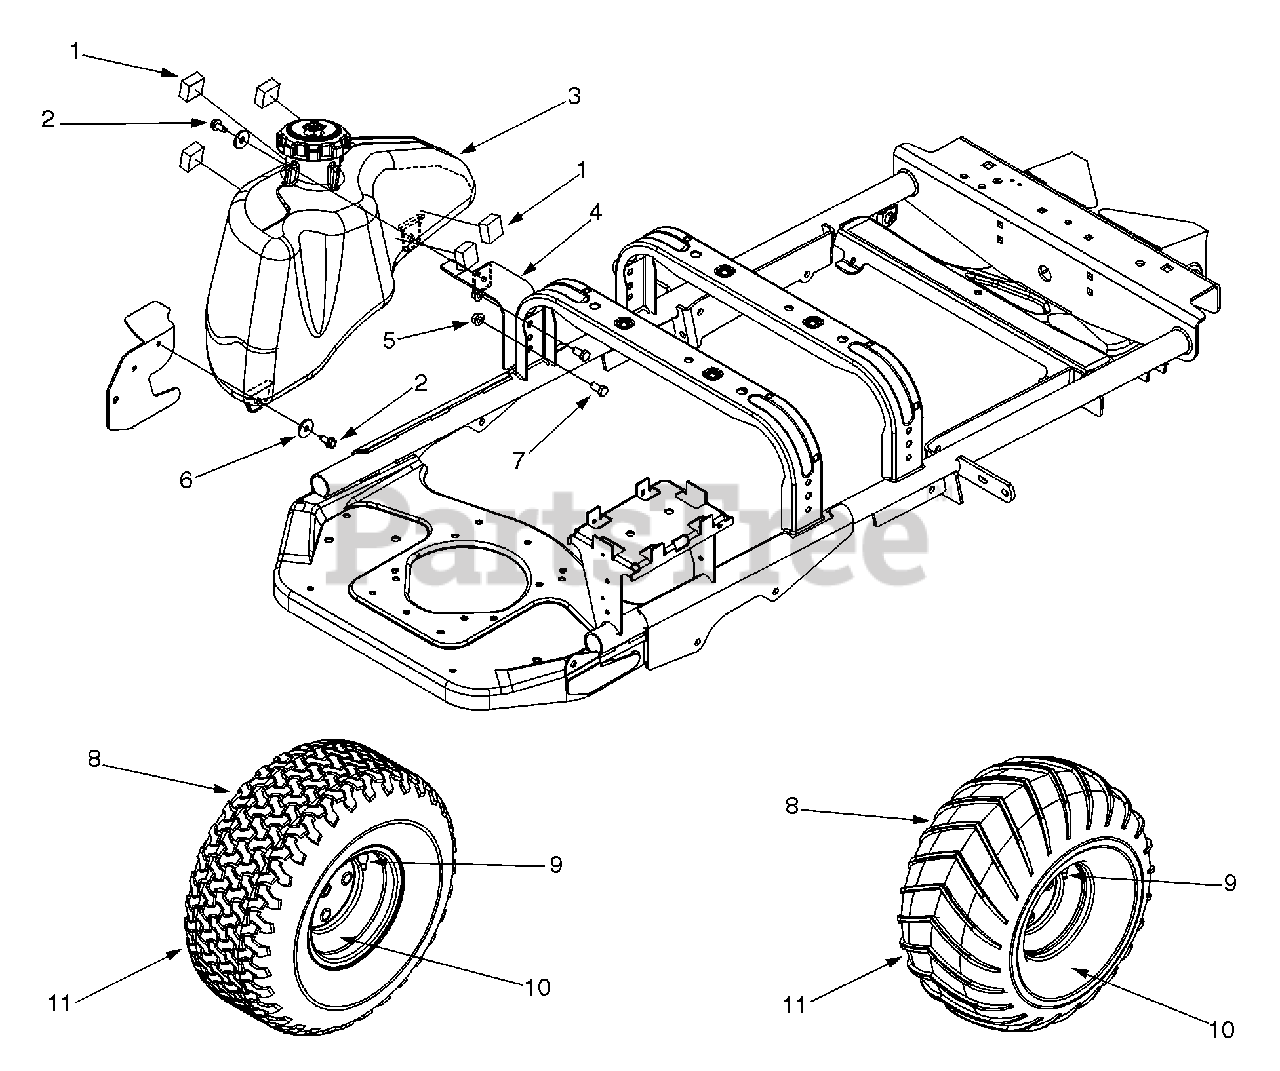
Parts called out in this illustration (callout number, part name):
1	Foam 1.25 x .62
2	Hex Washer Screw 5/16-18.0 x .75
3	Fuel Tank 4.0 gal
6	Flat Washer .344 x 1.125
7	Hex Cap Screw 3/8-16 x .75
8	Tire 22 x 11-8
10	Tubeless Air Valve
